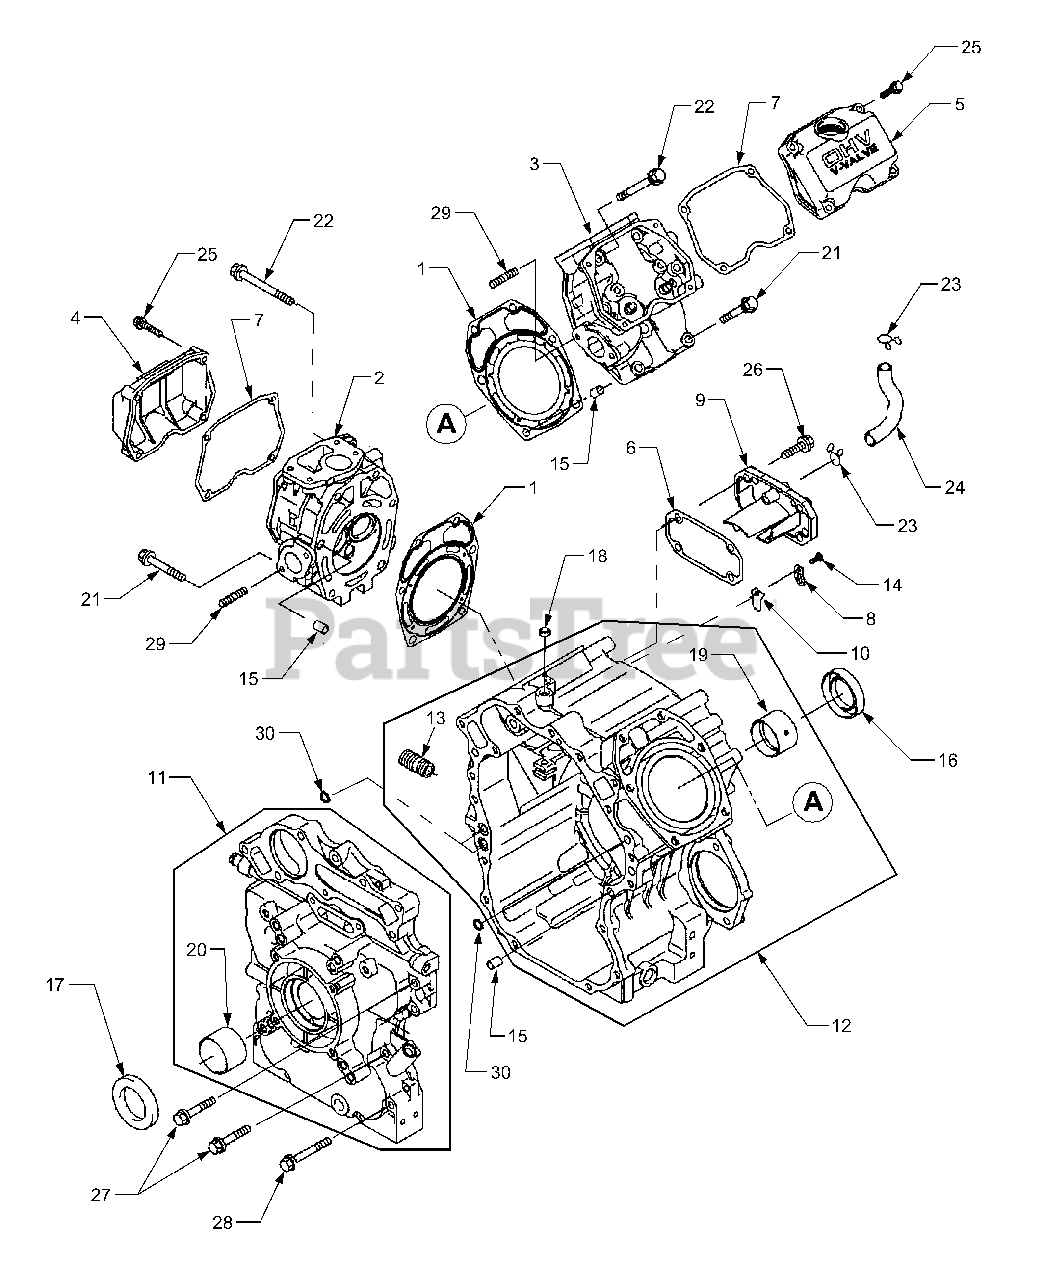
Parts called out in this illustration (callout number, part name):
2	Head, Cylinder
3	Head, Cylinder
4	Cover, Rocker
5	Cover, Rocker
6	Gasket, Breather
7	Gasket, Rocker Cover
8	Plate, Breather
9	Cover, Breather
10	Valve, Breather
11	Cover, Crankcase
12	Crankcase,
19	Bearing, Plane
20	Bearing, Plane
21	Bolt, M8 x 55
22	Bolt, M8 x 80
25	Bolt, Flange
26	Bolt, Flange
27	Bolt, Flange
28	Bolt, Flange
29	Bolt, Stud
